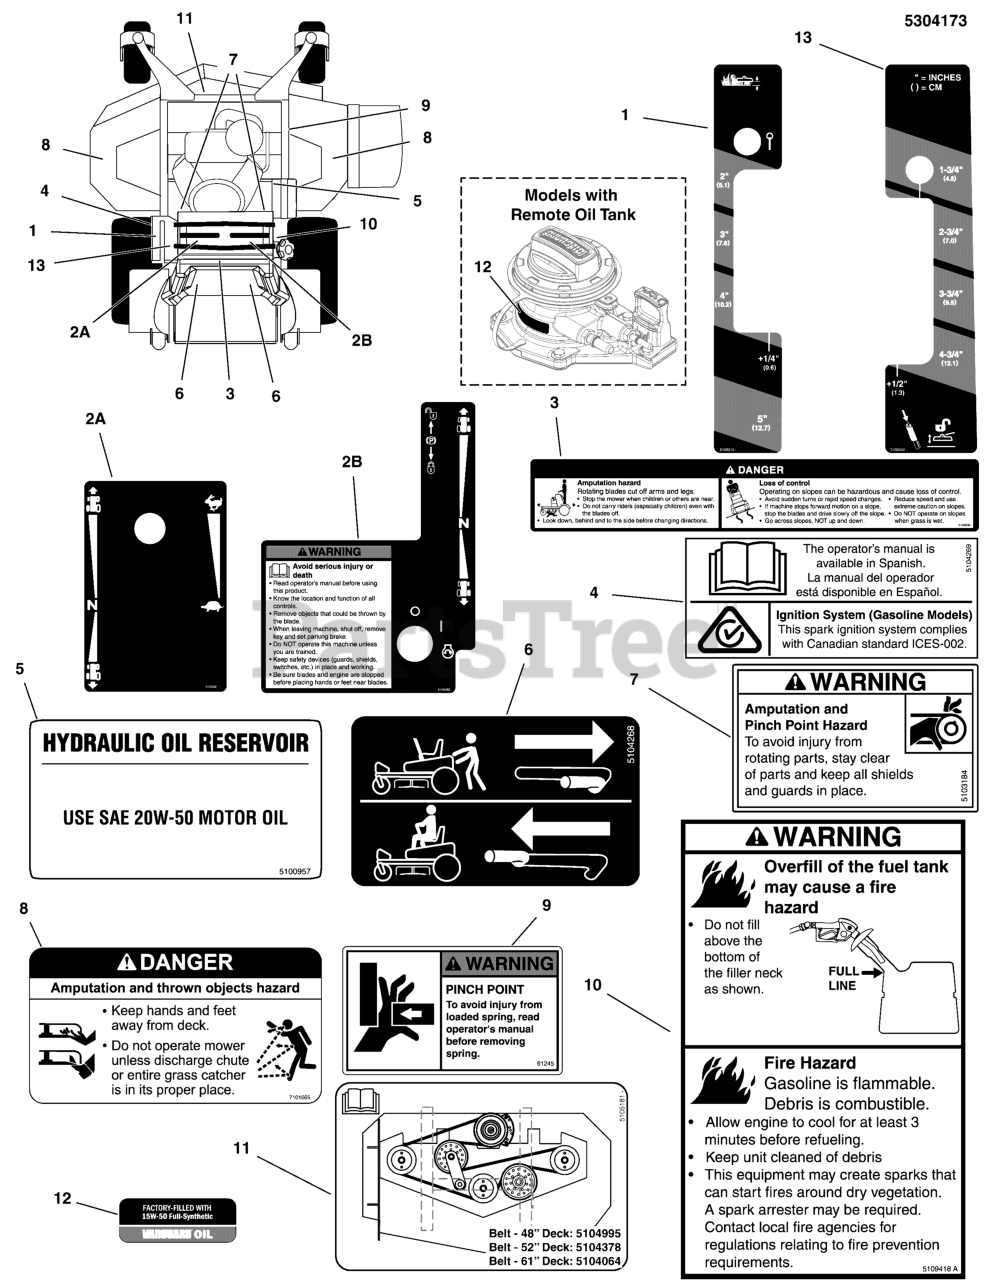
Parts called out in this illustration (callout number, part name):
1	DECAL, CUT HEIGHT, SRSZ2 & Z3
2A	DECAL, DASH PANEL, LH, CONTROLS
2B	DECAL, DASH PANEL, RH, WARNING/CONTROLS
3	DECAL, Danger
4	DECAL, SPANISH MANUAL, IGES, C-TICK
5	DECAL, HYDRAULIC OIL, SAE 20W50
6	DECAL, TRANSAXLE RELEASE, WB
7	DECAL, WARNING, HAND IN BELT, ENG ONLY
8	DECAL, DANGER DO NOT OPERATE W/O DEFLECT
9	DECAL, PINCH POINT
10	DECAL, WARNING, TANK OVERFILL
11	DECAL, BELT ROUTING, SRS-48-52-61
12	LABEL, OIL INFORMATION
13	DECAL, CUT HEIGHT, STAND ON
